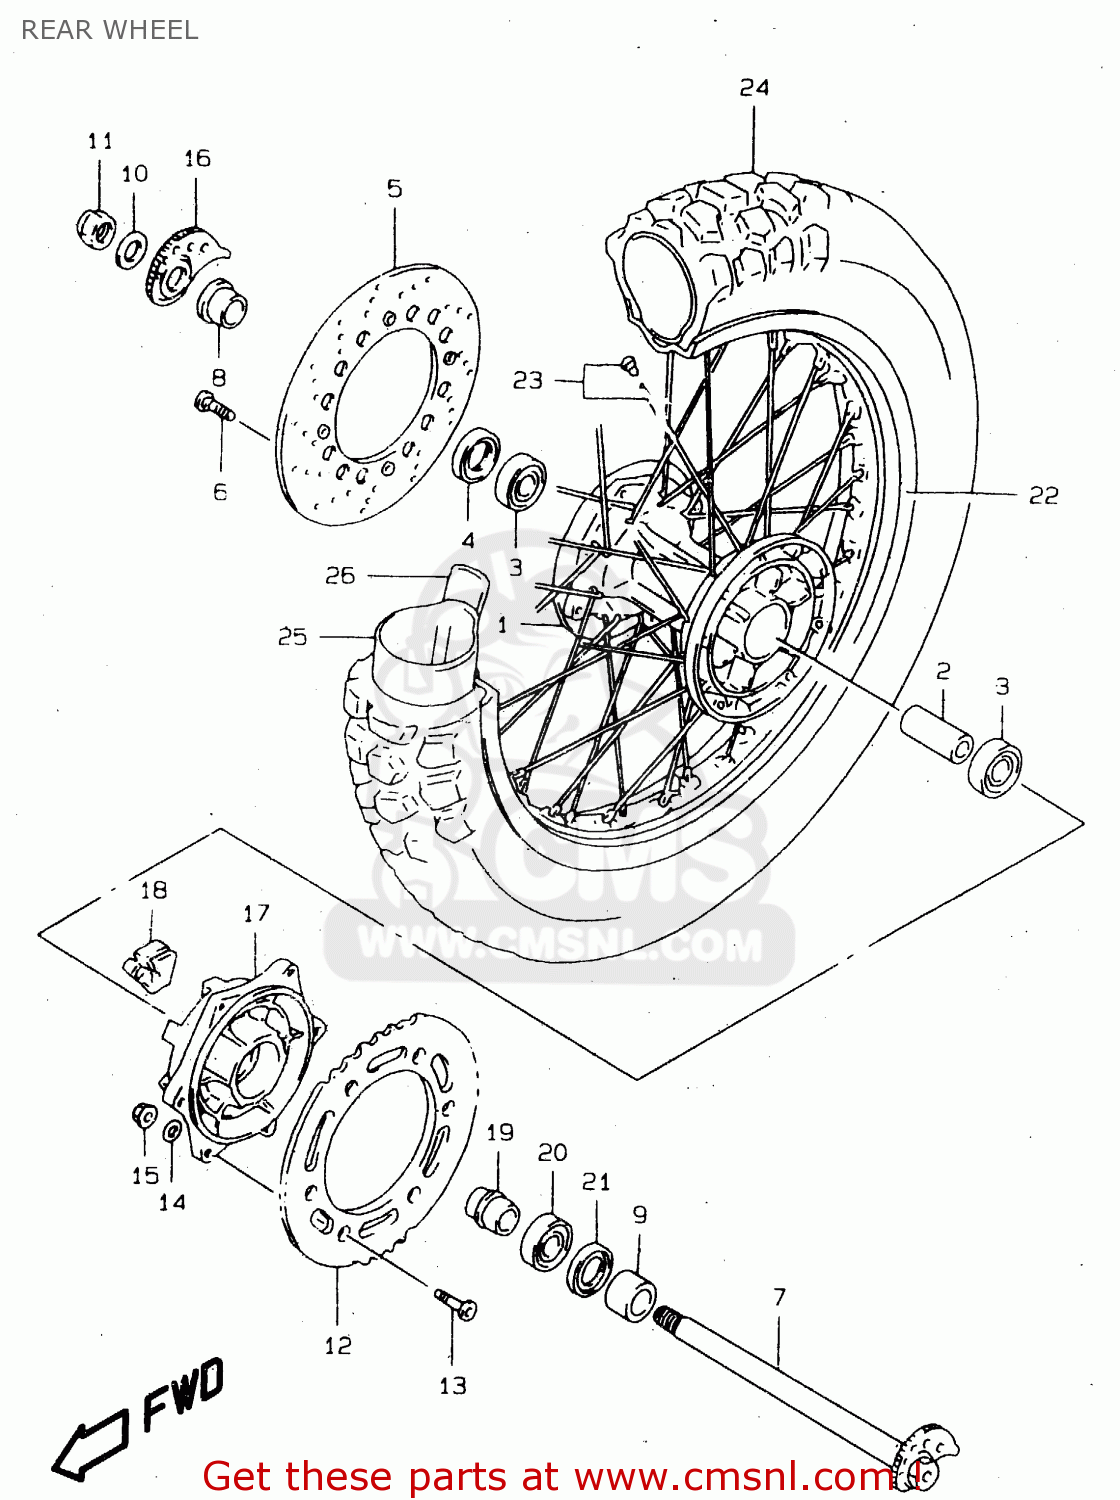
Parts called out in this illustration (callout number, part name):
1	HUB,RR WHEEL
2	SPACER,RR HUB BEARING
3	BEARING
4	SEAL,OIL(26X47X5)
5	DISC,RR BRAKE
6	BOLT,BRAKE DISC
7	AXLE,RR
8	SPACER,RR AXLE,R
9	SPACER,RR AXLE,L
10	WASHER(19X32X3.2)
11	NUT 18MM
12	SPROCKET,RR(NT:41-525)
13	BOLT(8X30.5)
14	WASHER
15	NUT
16	ADJUSTER,CHAIN,R
17	DRUM,RR SPROCKET MOUNTING
18	ABSORBER,RR HUB SHOCK
19	RETAINER,RR SPROCKET DRUM
20	BEARING(25X52X15)
21	SEAL,OIL(34X52X6)
22	RIM,REAR WHEEL (17XMT2.50)
23	SPOKE SET,RR WHEEL
24	TIRE,RR(120/90-17 64S)
25	TUBE ASSY,WHEEL INNER
26	PROTECTOR,WHEEL,INNER
